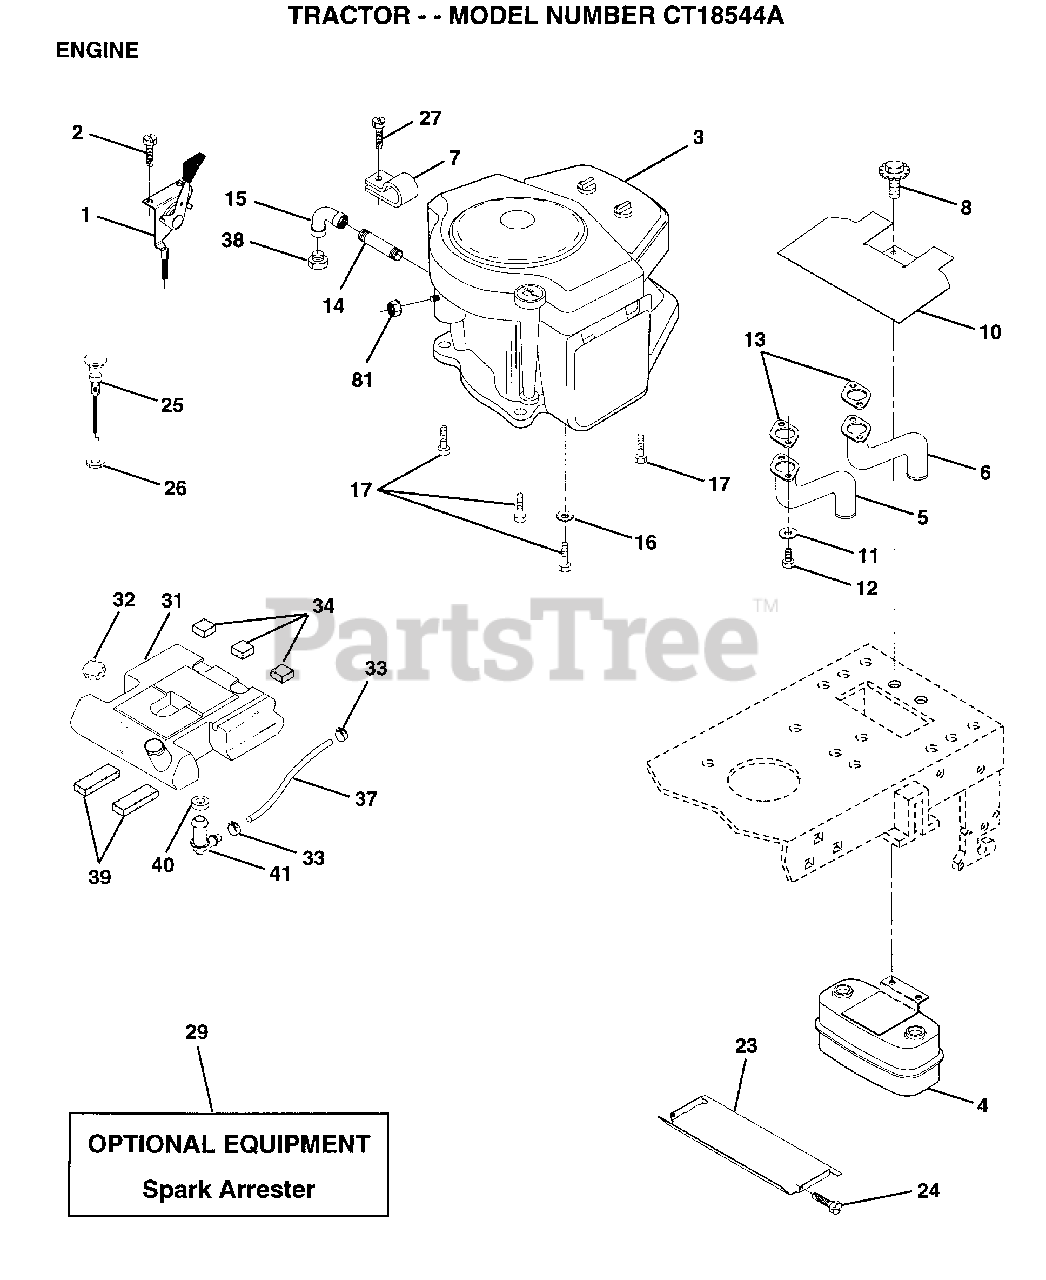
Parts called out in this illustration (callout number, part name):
2	SCREW LT
3	ENGINE, BRIGGS
4	MUFFLER.TW.LOTONE
5	EXHAUST.B&S.18.LH
6	EXHAUST.B&S.18.RH
7	CLAMP.TUBE.DBL.EN
8	BOLT.5/16-18.UNC
10	SHIELD.HEAT.
11	LOCKWASHER
13	GASKET MUFFLER
14	PIPE NIPPLE LT
15	ELBOW
16	LOCKWASHER
17	SCREW LT
23	HEAT SHIELD
24	SCREW
25	"CONTROL.CHOKE.51"""
26	"NUT,KEPS 3/8-24IM"
27	SCREW.10-24X1/2
31	TANK FUEL REAR
32	CAP ASM FUEL
33	HOSE CLAMP
34	PAD-SPACER LT
35	SCREW
36	WASHER
37	FUEL LINE T
39	PAD IDLER TI
40	BUSHING OUTLET T
41	STEM.TANK.FUEL
81	NUT
